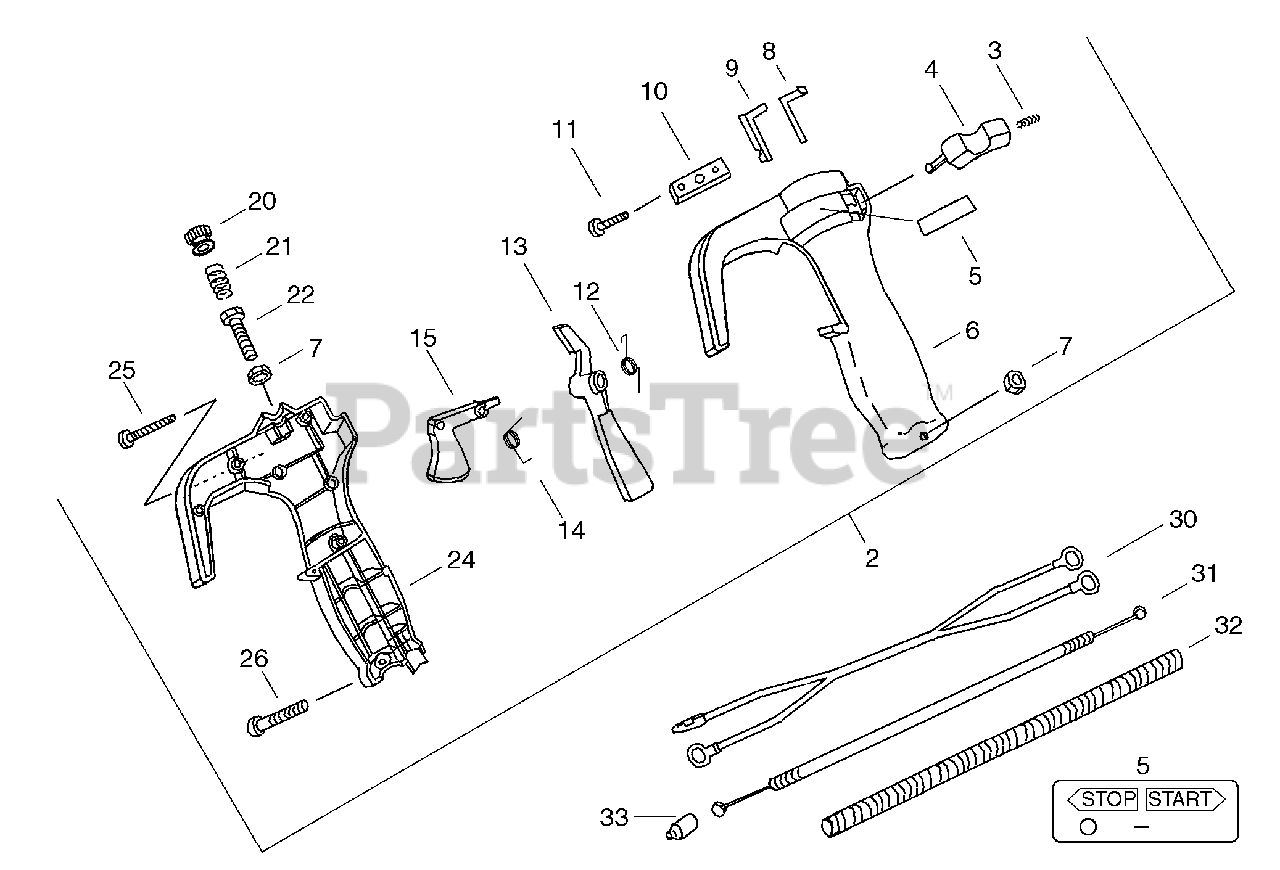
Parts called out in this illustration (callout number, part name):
2	THROTTLE CONTROL ASSY
4	SWITCH, START-STOP
5	LABEL - STOP/START
6	GRIP, HANDLE - LEFT
13	LOCKOUT, THROTTLE
15	TRIGGER, THROTTLE
24	HANDLE, CONTROL - RIGHT
30	WIRE, LEAD
31	CABLE, THROTTLE
32	TUBE, FLEX
33	CAP, DUST
